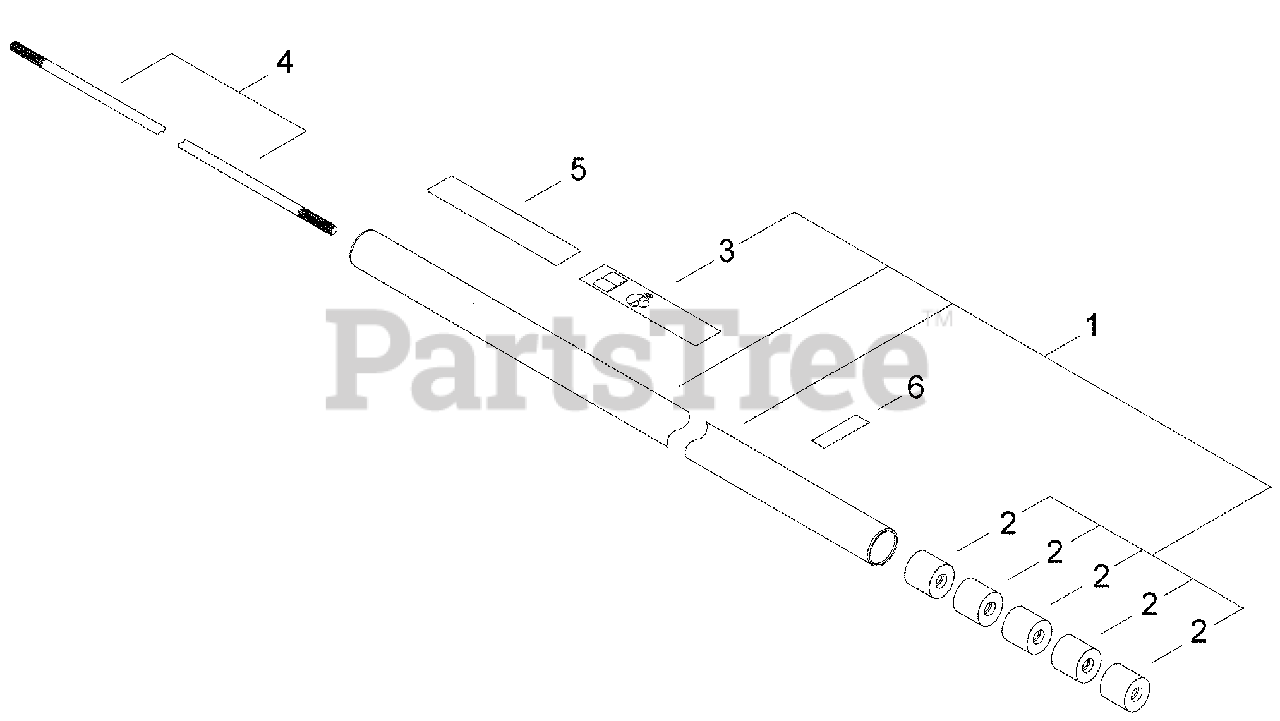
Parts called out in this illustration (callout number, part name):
1	OUTER TUBE ASSY
2	BUSHING
3	LABEL - CAUTION
4	PIPE, MAIN
5	LABEL - SWISHER E4
6	LABEL - INSTRUCTION
